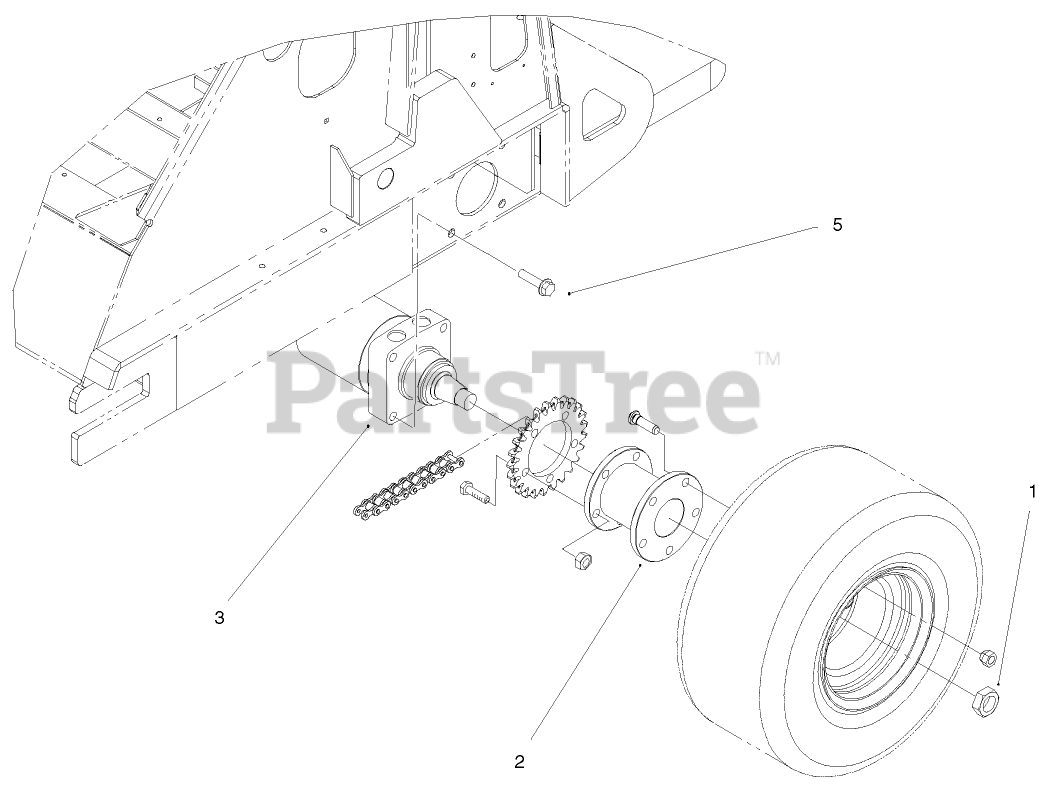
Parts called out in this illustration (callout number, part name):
1	NUT-LOCK
2	Hub-Rear
3	HYD MOTOR ASM
5	SCREW-HHF
